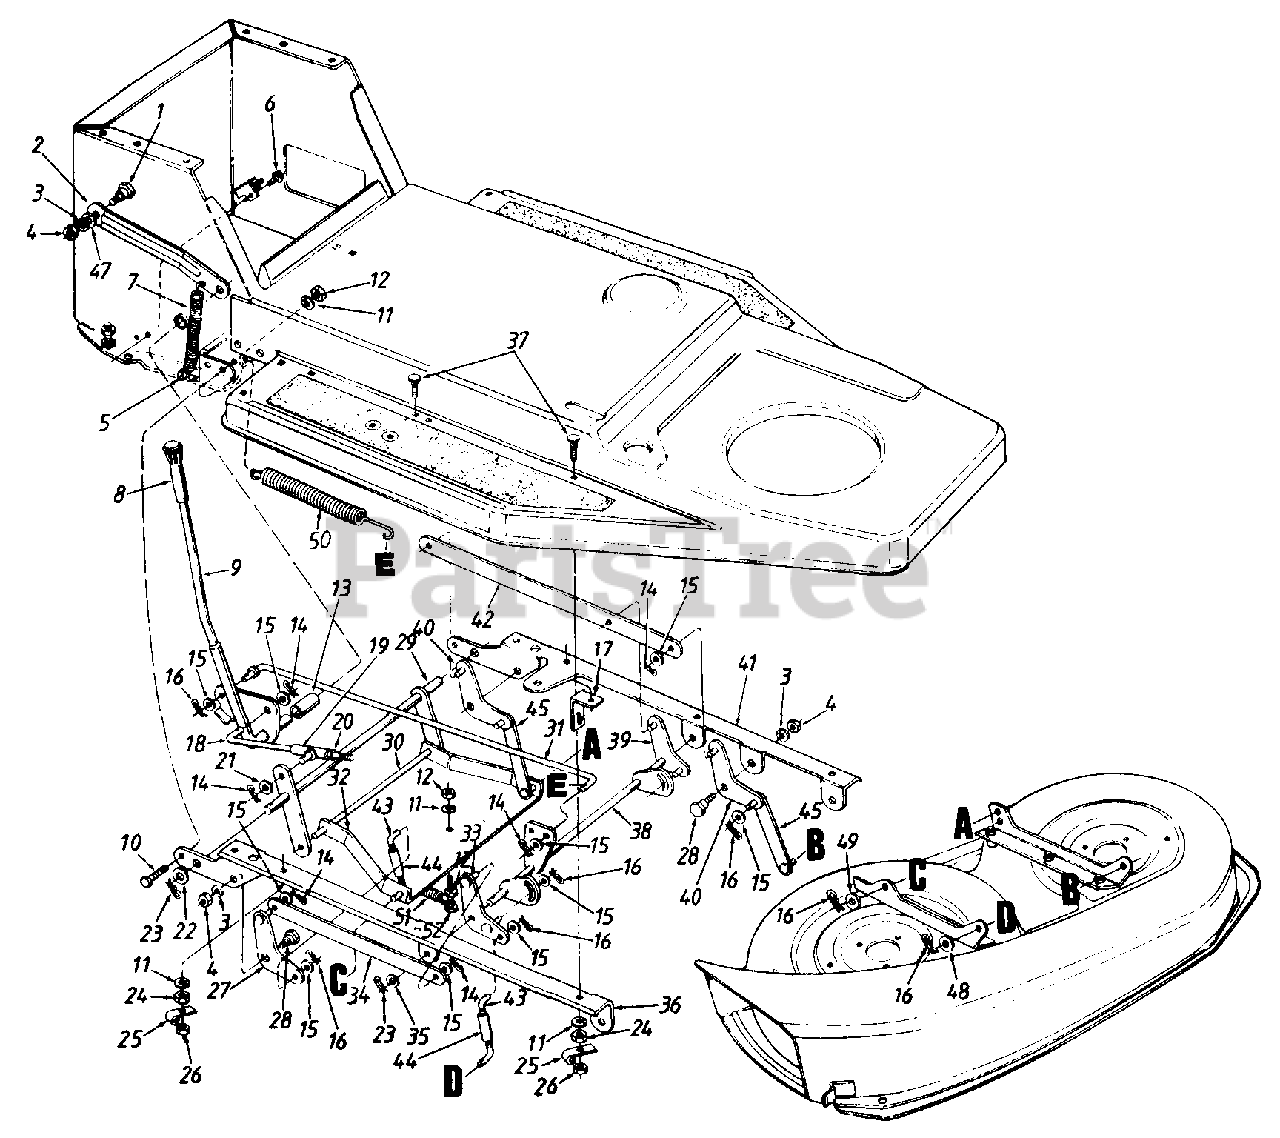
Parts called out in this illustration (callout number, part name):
1	Shld. Bolt .5" Dia. x .34" Lg.
4	Hex Nut 3/8-16 Thd.
5	Hex Bolt 1/4-28 x 1.25" Lg.
6	Hex TT-Tap Scr. 1/4-20 x .5" Lg.
8	Grip
9	Deck Lift Handle Ass'y.
10	Hex Wash. TT-Tap Scr. 5/16-18 x .62" Lg.
11	L-Wash. 5/16" I.D.
12	Hex Nut 5/16-18 Thd.
13	Spacer 5/8" I.D. x .78"
14	Cot-Pin 3/32" Dia. x .75" Lg.
15	Fl-Wash. .406" I.D. x .75" O.D.
16	Internal Cot-Pin 5/16" Dia.
19	Pivot Sleeve Ass'y.
20	Hex L-Nut 3/8-16 Thd.
21	Thrust Washer .382" I.D.
22	Fl-Wash. .635" I.D. x .93" O.D.
23	Cot-Pin 1/8 Dia. x 1.25" Lg.
24	Hex Nut 5/16-24 Thd.
25	Harness Retainer
26	Hex Cent. L-Nut 5/16-24 Thd.
27	Deck Pivot Brkt. Ass'y.- R.H. Rear
28	Shld. Bolt .625" Dia. x .170" Lg.
31	Deck Lift Rod
44	Adj. Lift Link Ass'y.
45	Deck Lift Link Ass'y.
47	Fl-Wash. .531" I.D. x .94"
48	Fl-Wash. .406" I.D. x .75"
49	Fl-Wash. 3/8" I.D.
50	Ext. Spring .87" Dia.
51	Ext. Spring 11" Lg.
52	Hex Bolt 5/16-18 x 7/8" Lg.
